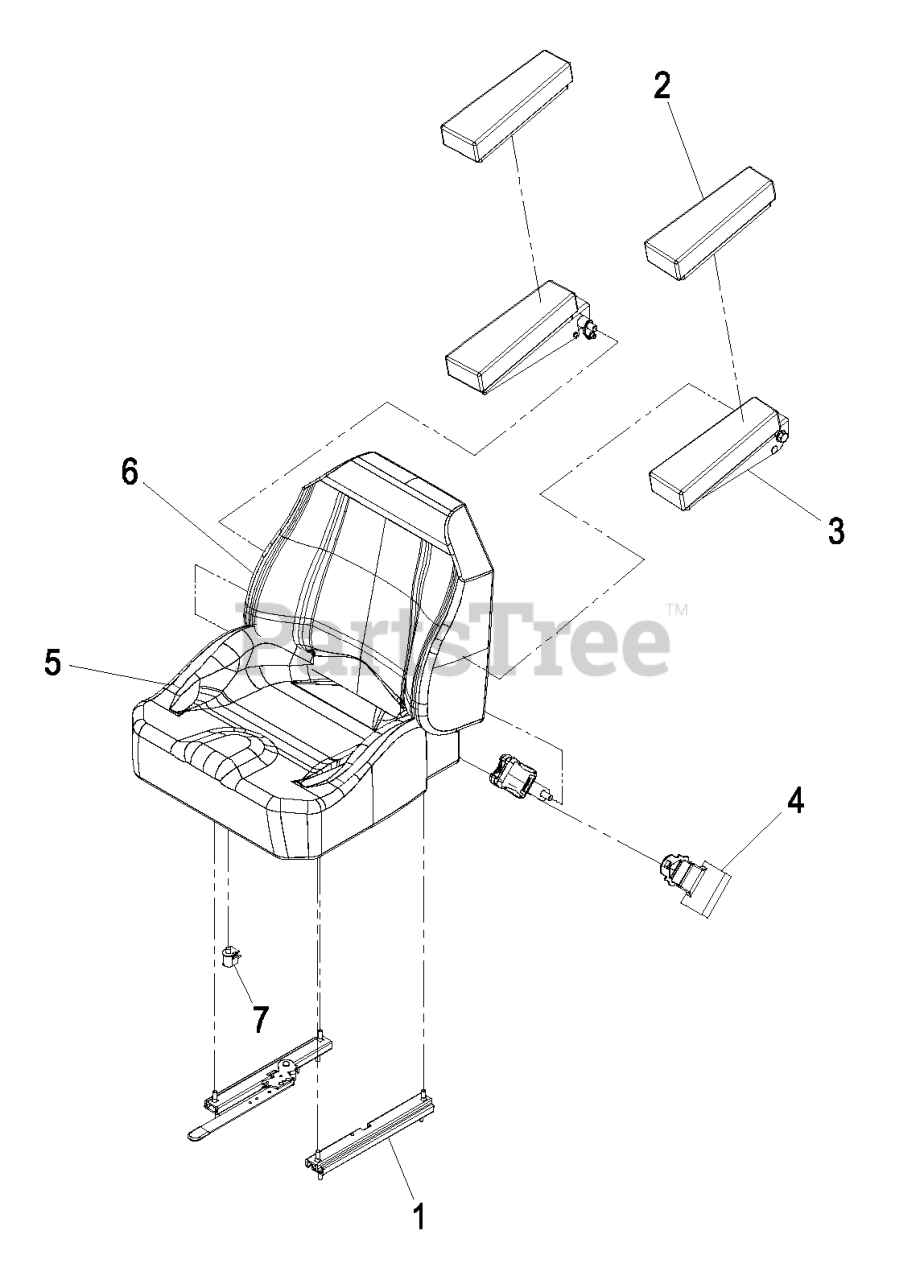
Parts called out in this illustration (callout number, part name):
1	SEAT TRACK SET
2	SET,ARM REST PADS
3	KIT,ARM REST SET
4	SEAT BELT KIT
5	COVER,CUSHION
6	COVER,BACK
7	SWITCH-BAIL
